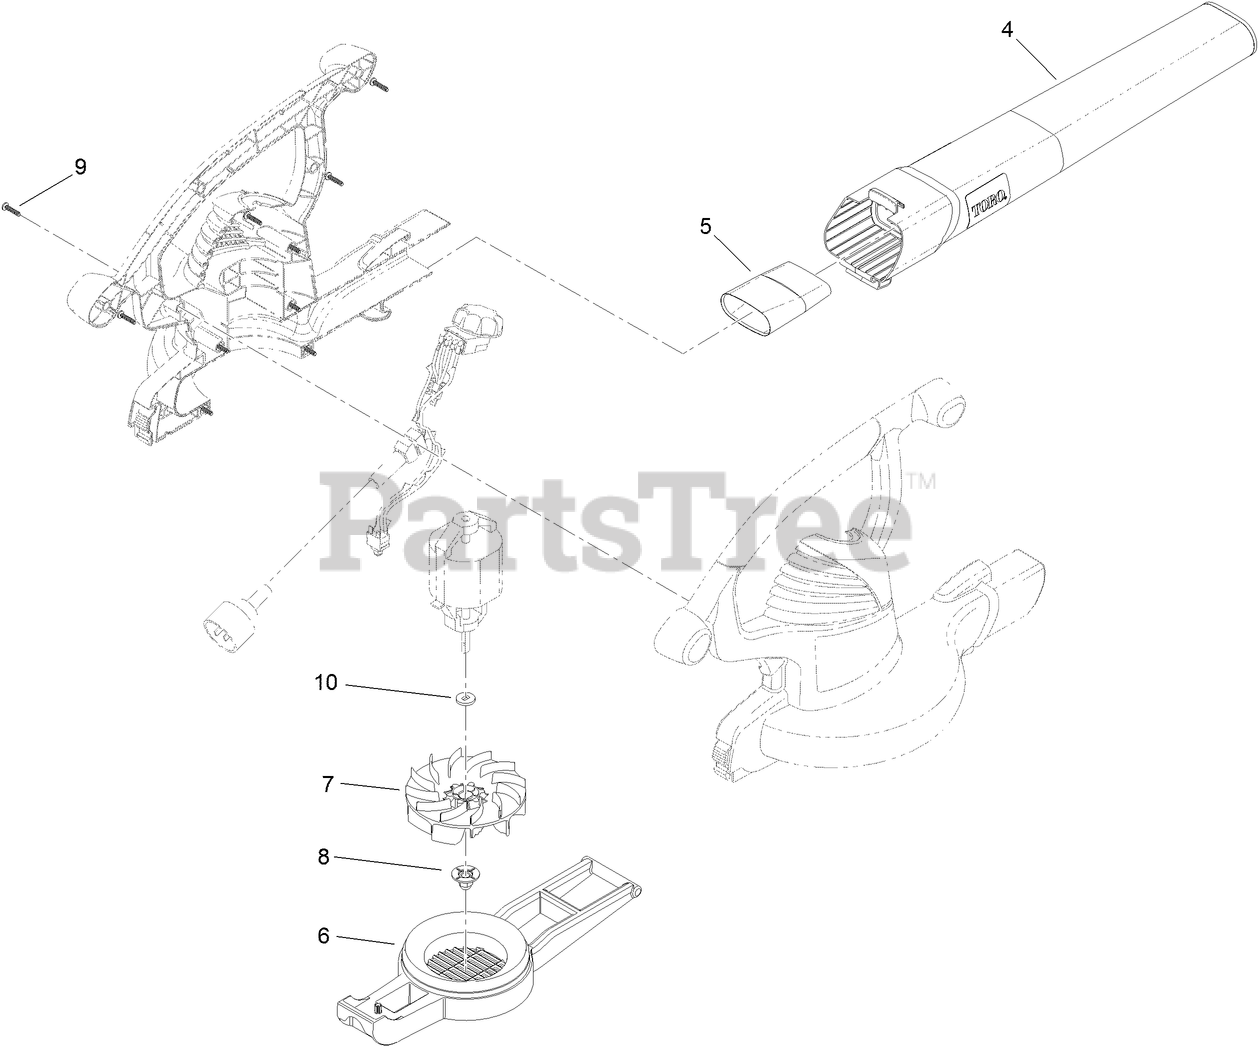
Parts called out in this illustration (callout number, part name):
4	TUBE-BLOWER
5	TUBE-EXTENSION, SUPER
6	COVER-INLET
7	IMPELLER-PLASTIC
8	NUT-IMPELLER
9	SCREW-PPH
10	WASHER-IMPELLER
